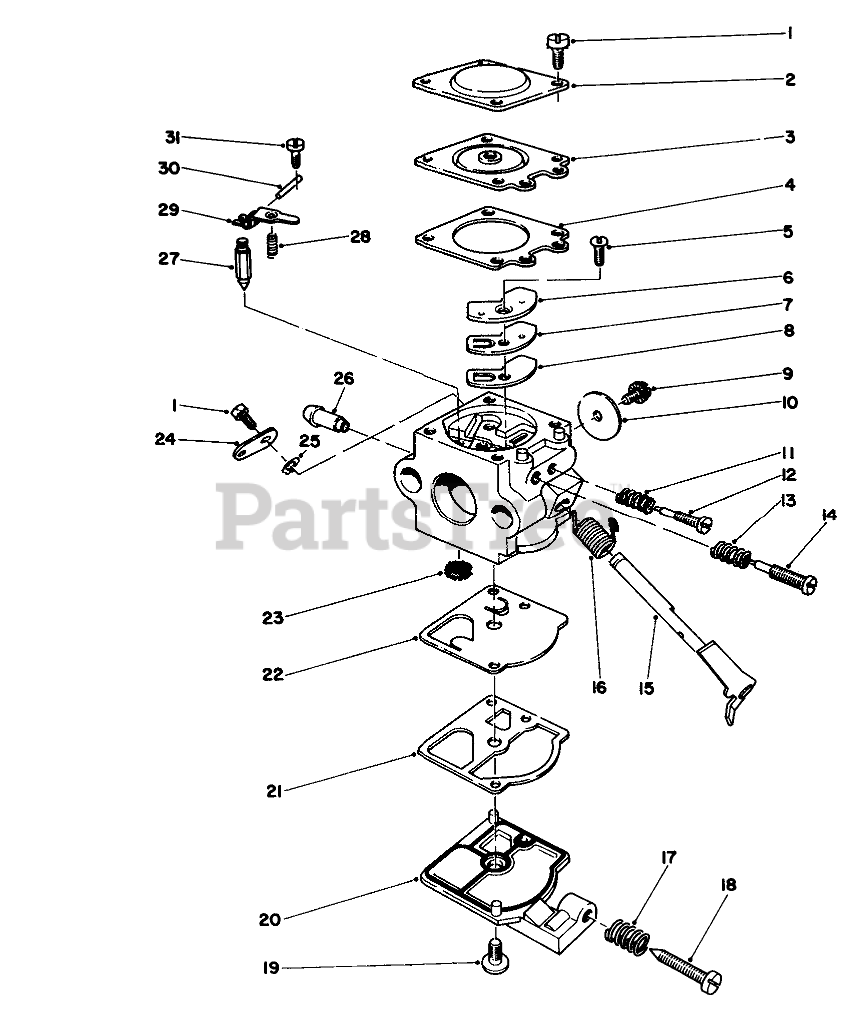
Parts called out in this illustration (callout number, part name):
1	Screw
2	Cover, Diaphragm
3	METERING DIAPHRAGM
4	Gasket, Diaphragm
5	Screw-Circuit Plate
6	Plate, Circuit
7	Diaphragm Circuit Plate
8	Gasket-Circuit Plate
9	Screw-Throttle Valve
10	Valve-Throttle
11	Spring, Needle
12	Needle-Idle
13	Spring, HS Needle
14	Needle, HS
15	Shaft Assembly-Throttle
16	Spring-Throttle Lever
17	Spring-Idle Screw
18	Screw-Idle Adjust
19	Screw
20	Cover-Fuel Pump
21	PUMP GASKET
22	Diaphragm Fuel Pump
23	Inlet Screen
24	Lever-Throttle
25	Ring-Throttle Retainer
26	Fitting Fuel Inlet
27	INLET NEEDLE VALVE
28	METERING LEVER SPRING
29	Lever Metering
30	Metering Lever Pin
31	Screw-Metering Pin
